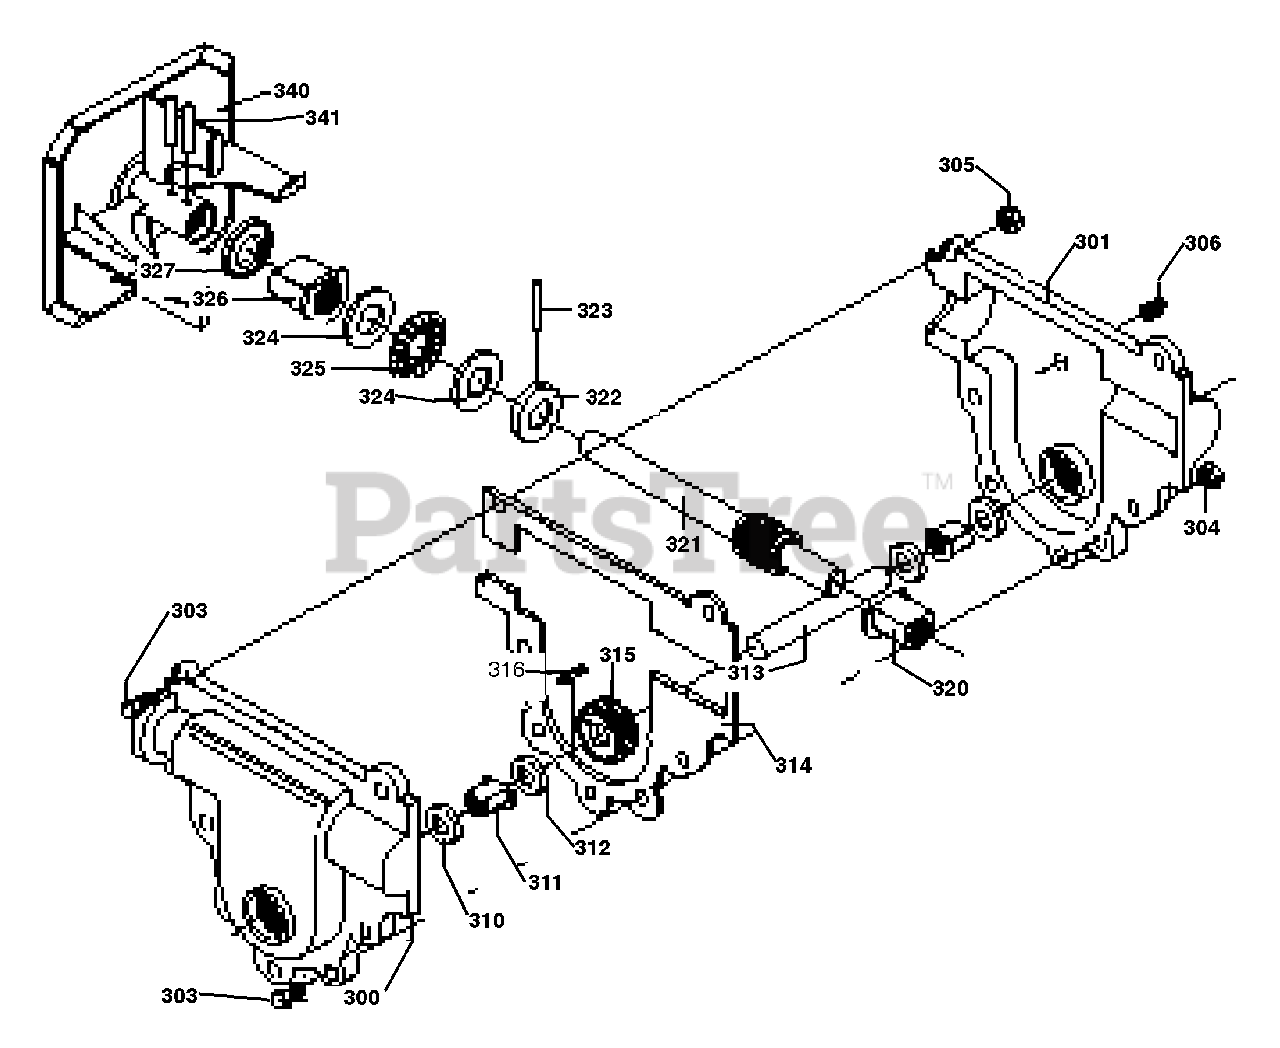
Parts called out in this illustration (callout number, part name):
300	CASE, GEAR RH
301	CASE, GEAR LH
303	SCREW, 1/4-20 X .75
304	NUT, 1/4-20 WDFL
305	NUT, 1/4-20 HEXKEPS
306	SCREW, 3/8-16 X .50
311	BEARING, FLANGE
312	WASHER, FLAT
313	SHAFT, AUGER
314	GASKET, GEAR CASE
316	KEY, WDRF #61
320	BEARING, FLANGE
321	SHAFT, WORM IMP
322	COLLAR, THRUST
323	PIN, SPRING
324	WASHER, FLAT
325	BEARING, ROLL
326	BEARING, FLANGE
340	IMPELLER, ASSY
341	PIN, SPRING
